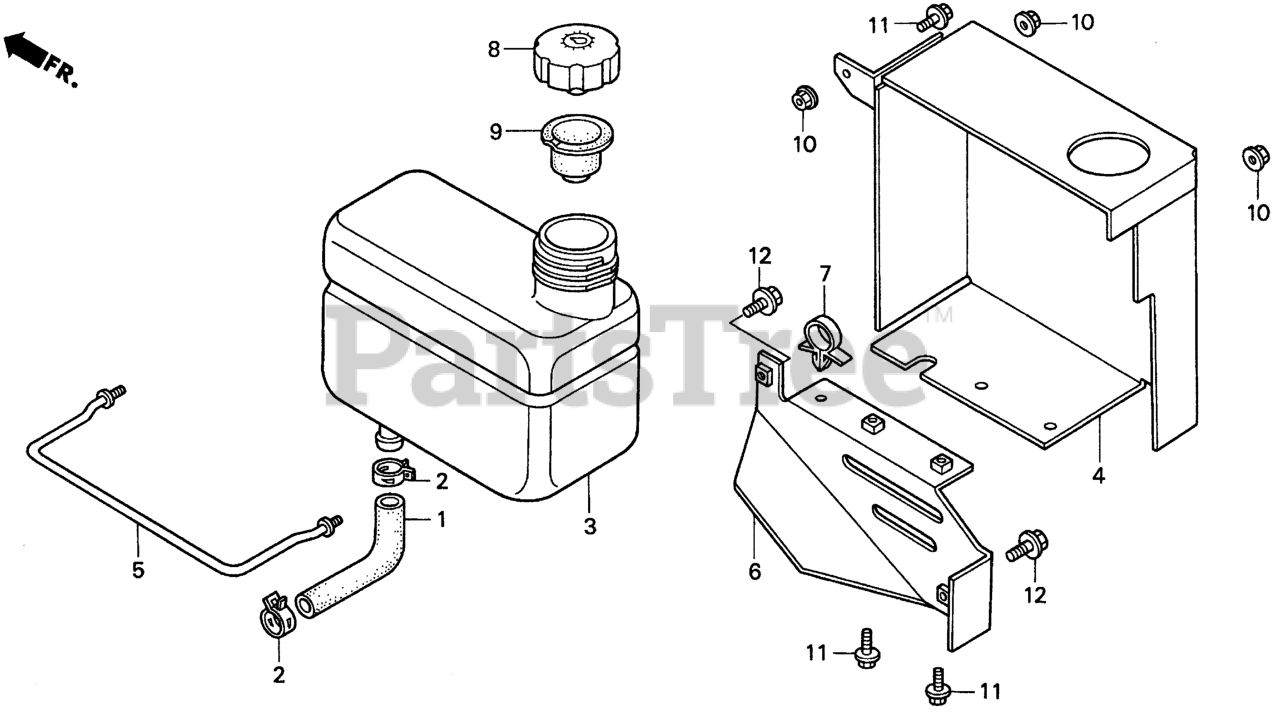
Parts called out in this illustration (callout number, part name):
2	CLAMP, TUBE (D19)
4	COVER, OIL TANK
5	ROD, OIL TANK
6	BRACKET, OIL TANK COVER
7	HOLDER, TUBE
8	FRAME, OIL CAP
9	GASKET, OIL CAP
10	NUT, FLANGE (6MM)
11	BOLT, FLANGE (6X12) Use from Engine SN 2086984.
12	BOLT, FLANGE (8X14)
